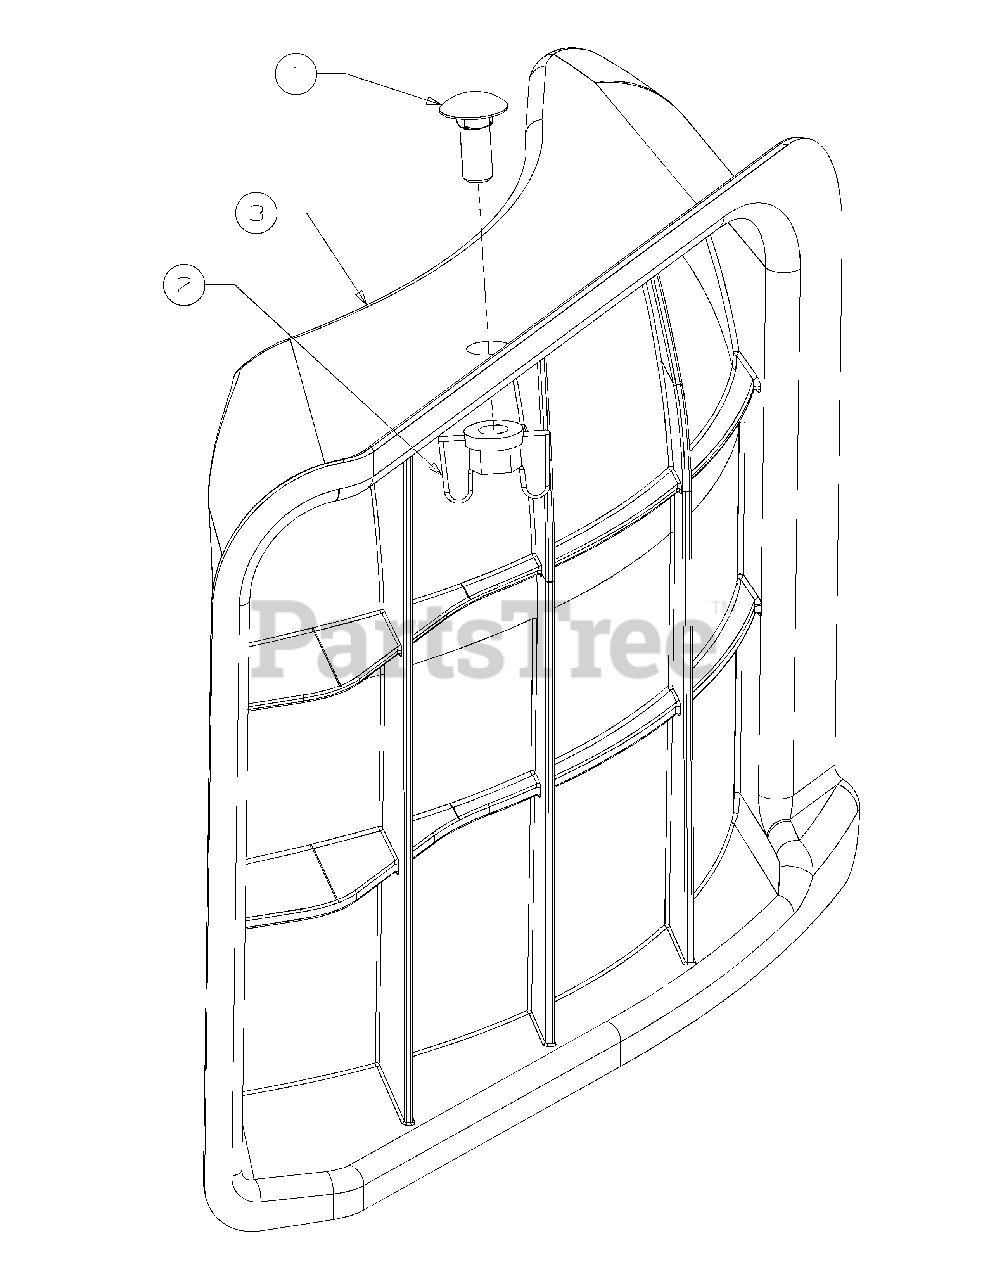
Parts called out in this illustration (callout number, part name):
1	Carriage Screw, 1/4"
2	Plastic Wing Nut, 1/4"
3	Mulch Plug
